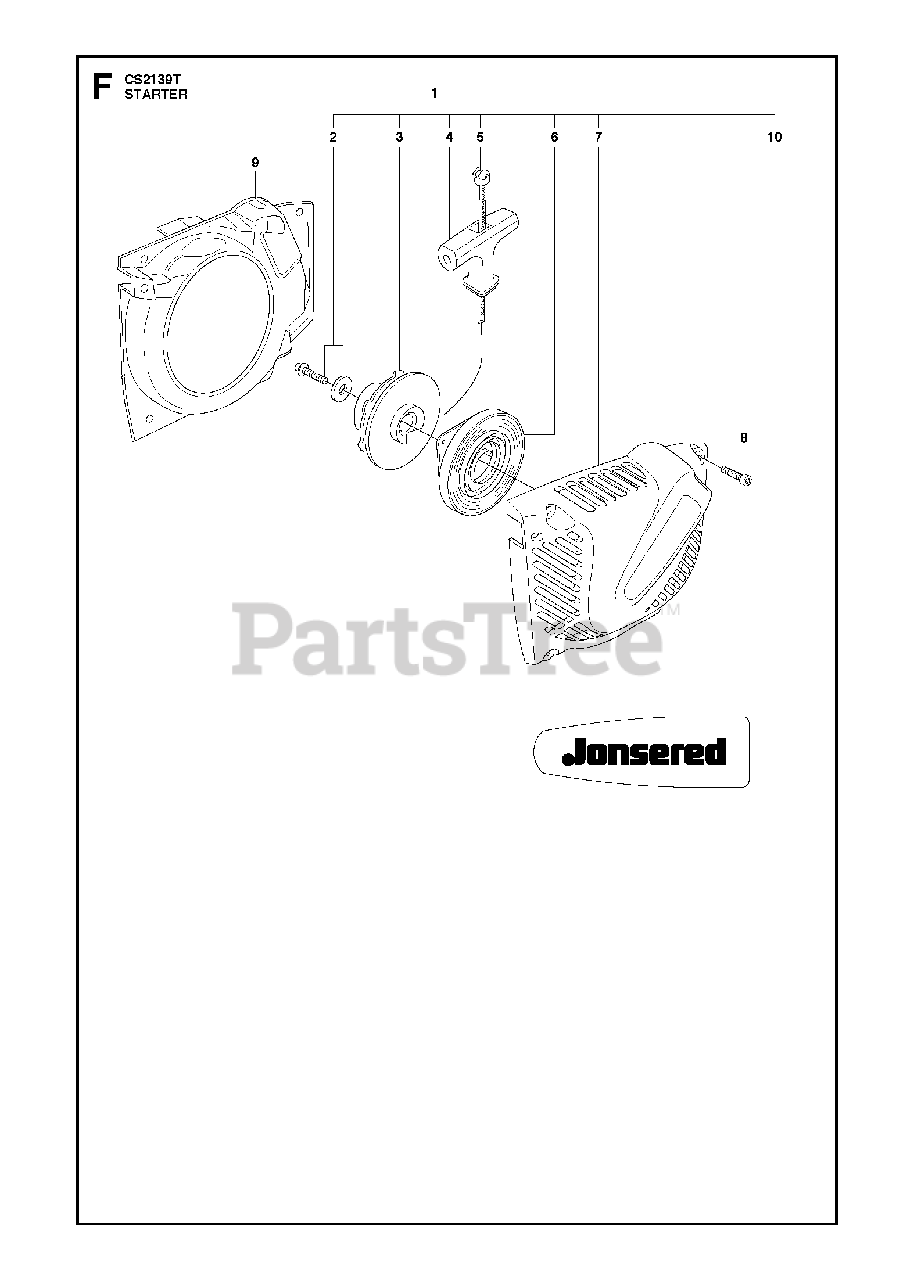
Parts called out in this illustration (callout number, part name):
1	STARTER ASSY
2	SCREW
3	STARTER PULLEY
4	HANDLE
5	STARTER ROPE
6	RECOIL SPRING
7	STARTER HOUSING
9	AIR CONDUCTOR
10	LABEL
